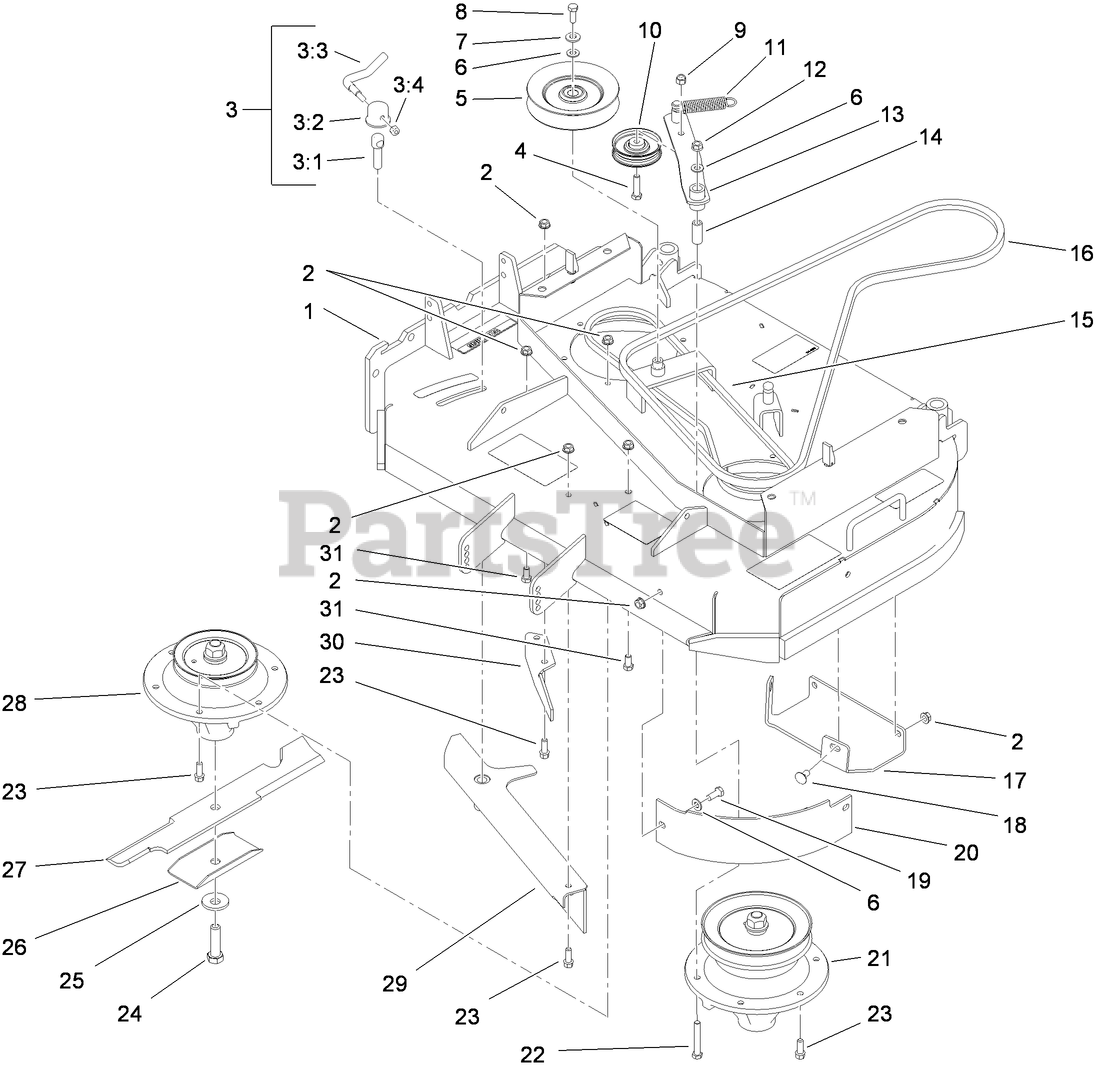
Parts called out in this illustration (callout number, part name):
1	DECK ASM
2	NUT-HHF, WHIZ
3	LEVER ASM
3:1	Screw-Lock
3:2	CAP-LOCK
3:3	Lever-Lock
3:4	NUT-LOCK, NI
4	SCREW-HH
5	PULLEY-IDLER
6	WASHER-FLAT
7	WASHER-BELLEVILLE
8	SCREW-HH
9	NUT-LOCK, NI
10	PULLEY-IDLER
11	SPRING-EXTENSION
12	NUT-HF
13	IDLER ARM ASM
14	SLEEVE-PIVOT, IDLER
15	BELT-V
16	BELT-V
17	PLATE-SKID
18	SCREW-CARR
19	SCREW-HH
20	BAFFLE-FRONT, LH
21	SPINDLE ASM
22	SCREW-HH
23	SCREW-HWH
24	SCREW-BLADE
25	Washer-Blade Bolt, Heavy
26	STIFFENER-BLADE
27	BLADE-18IN, HI FLOW
28	SPINDLE ASM
29	ADJUST BAFFLE ASM
30	BAFFLE-DISCHARGE
31	SCREW-HH
